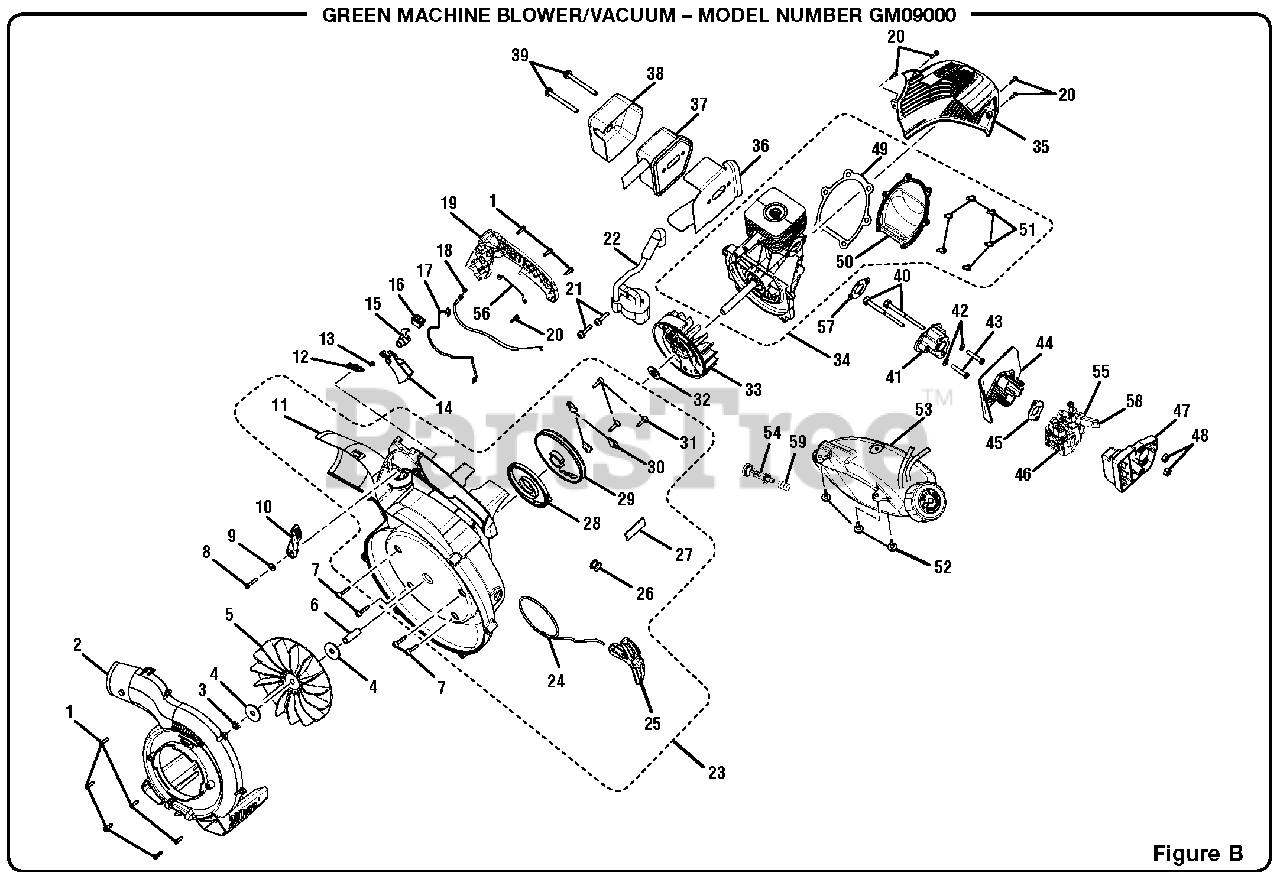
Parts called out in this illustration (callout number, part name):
1	Screw (10-14 x 3/4 in.)
2	Outer Volute
3	Lock Nut (3/8 in.)
5	Fan
7	Screw (M4 x 17 mm, T.F.)
8	Screw (8-14 x 1 in., T.F.)
10	Cruise Lever
11	Lower Housing
12	Throttle Lever
13	Screw (M3.5 x 7.5 mm)
14	Throttle Trigger
15	Trigger Lock
16	Momentary Contact Switch
17	Wire Assembly
18	Throttle Cable
19	Handle Cover
20	Screw (M4 x 18 mm)
21	Screw (M4 x 19 mm, T.F.)
22	Ignition Module
23	Lower Housing w/Starter
24	Starter Rope (42 in.)
25	Starter Grip
28	Spring & Container
29	Starter Pulley
30	Pulley Retainer
31	Screw (M4 x 14 mm, T.F.)
32	Washer
33	Flywheel Assembly
34	Short Block Assembly
35	Engine Cover
36	Muffler Gasket
37	Muffler Assembly
38	Muffler Heat Shield
39	Screw (10-24 x 2-1/8 in.)
40	Screw (10-24 x 2.5 in.)
43	Screw (M5 x 25 mm)
45	Heat Dam Gasket
46	Carburetor
47	Air Box Base
48	Hex Nut (10-24)
49	Crankcase Cover Gasket
50	Crankcase Cover
51	Screw (M4 x 12 mm)
52	Screw (M4 x 14 mm, Shoulder)
53	Fuel Tank Assembly w/Cap
54	Fuel Filter
55	Primer Bulb
56	Ground Wire Kit
57	Intake Gasket
58	Choke Lever
59	Spring Clamp
